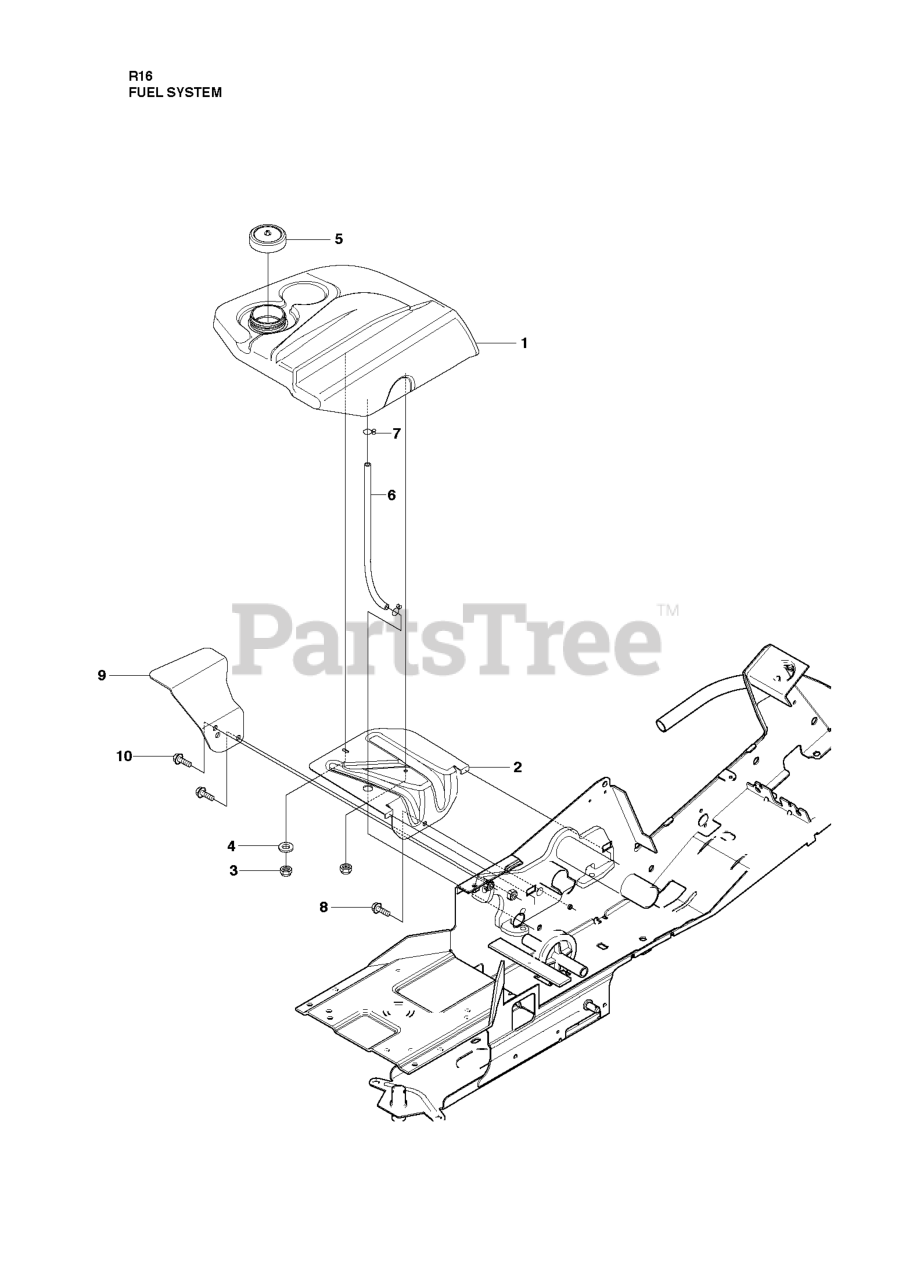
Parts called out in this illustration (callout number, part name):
3	LOCKNUT M6
4	WASHER
10	Screw M10x25
